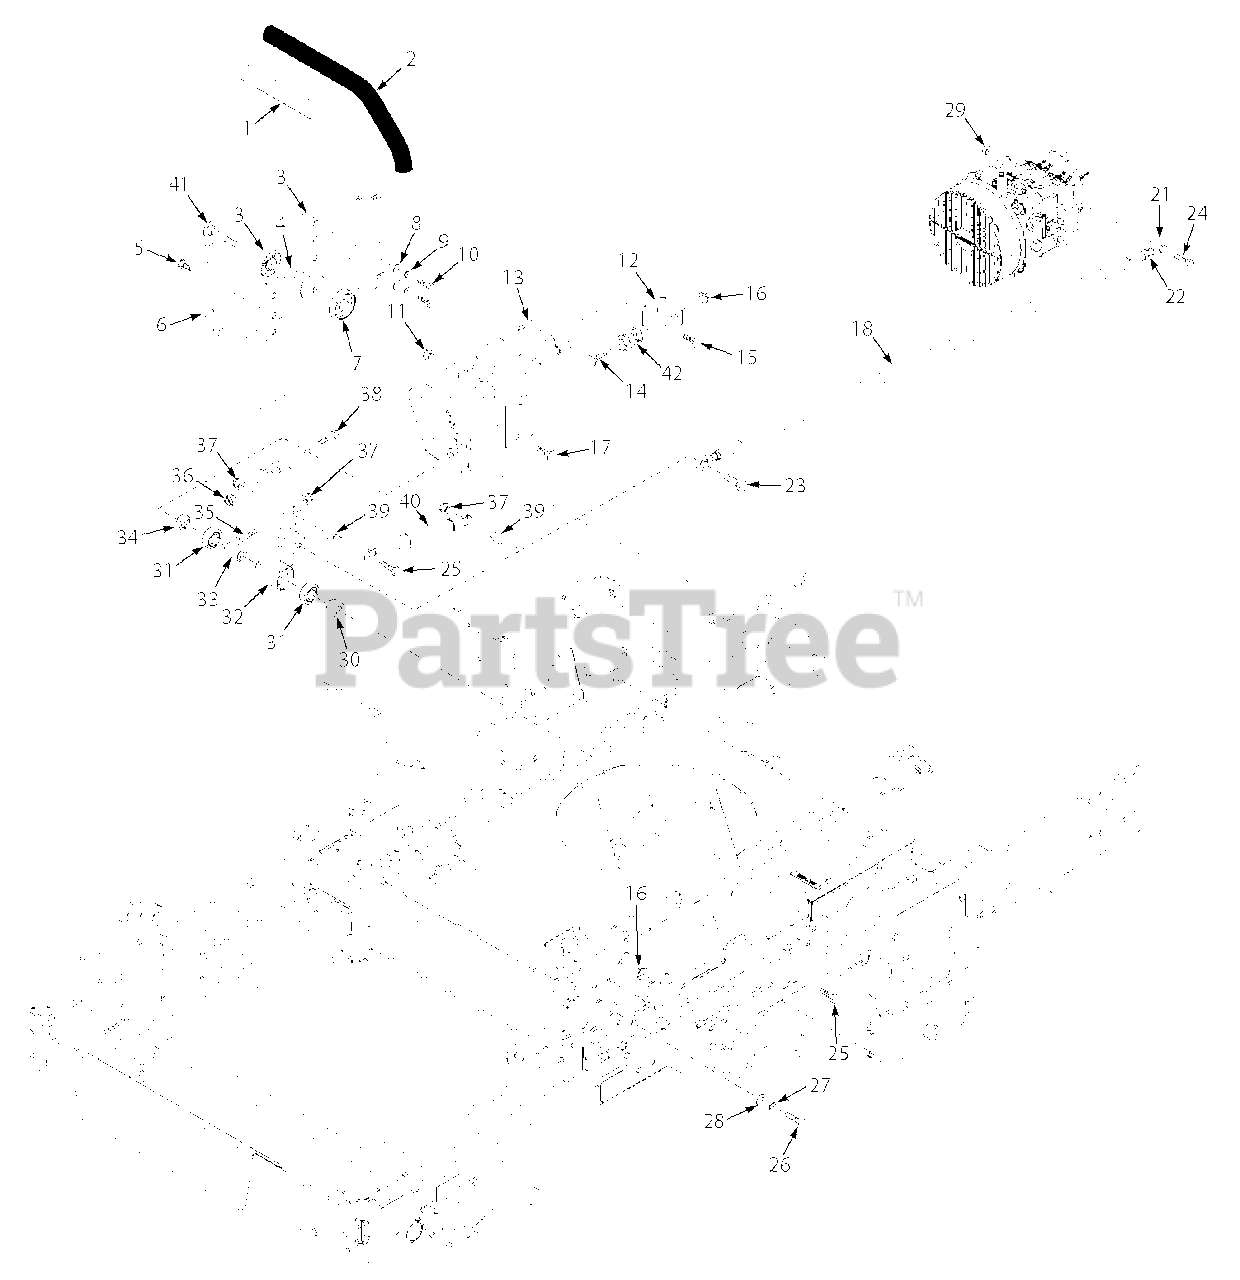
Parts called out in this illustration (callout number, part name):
1	Handle Bar w/Grip - LH
1	Handle Bar w/Grip - RH
2	Grip, Control Lever
3	Pivot, Control Lever
4	Spacer, Rubber
5	Bolt, Hex Head Serrated Flange 5/16-18 x 3/4"
6	Actuator, Switch
7	Knob, Control Handle
8	Flatwasher, 3/8-.391 x .938 x .105
9	Lockwasher, 3/8
10	Bolt, Hex Head 3/8-16 x 1"
11	Nut, Flange Elastic Stop 1/4-20
12	Mounting Bracket, Spring Return
13	Mounting Weldment, LH Control
13	Mounting Weldment, RH Control
14	Bolt, Carriage 5/16-18 x 3/4"
15	Bolt, Carriage 1/4-20 3/4"
16	Nut, Serrated Flange 5/16-18
17	Bolt, Carriage 5/16-18 x 3/4"
18	Linkage Assy., Pump Control
19	Rod End, Male - LH
20	Nut, 3/8-24 UNF LH Jam
21	Rod End, Male - RH
22	Nut, 3/8-24 UNF Jam
23	Bolt, Hex Head 3/8-16 x 1-1/2"
24	Bolt, Hex Head 3/8-16 x 1-1/4"
25	Bolt, Hex Head 5/16-18 x 1-1/2"
26	Bolt, Hex Head 3/8-16 x 4-1/4"
27	Lockwasher, 3/8"
28	Flatwasher, 3/8-.391 x .938 x .105
29	Nut, Center Lock 3/8-16
30	Spacer, Controls
31	Bearing
32	Control Lever Weldment, RH
32	Control Lever Weldment, LH
33	Spacer, Bearing
34	Spacer, Controls
35	Bolt, Hex Head 5/16/-18 x 2"
36	Nut, Elastic Stop 3/8-16
37	Nut, Elastic Stop 5/16-18
38	Bolt, Hex Head 3/8-16 x 2"
39	Spacer, Dampener
40	Dampener
41	Bolt, Carriage 3/8-16 x 1-1/2"
42	Return Spring, Control Arm
